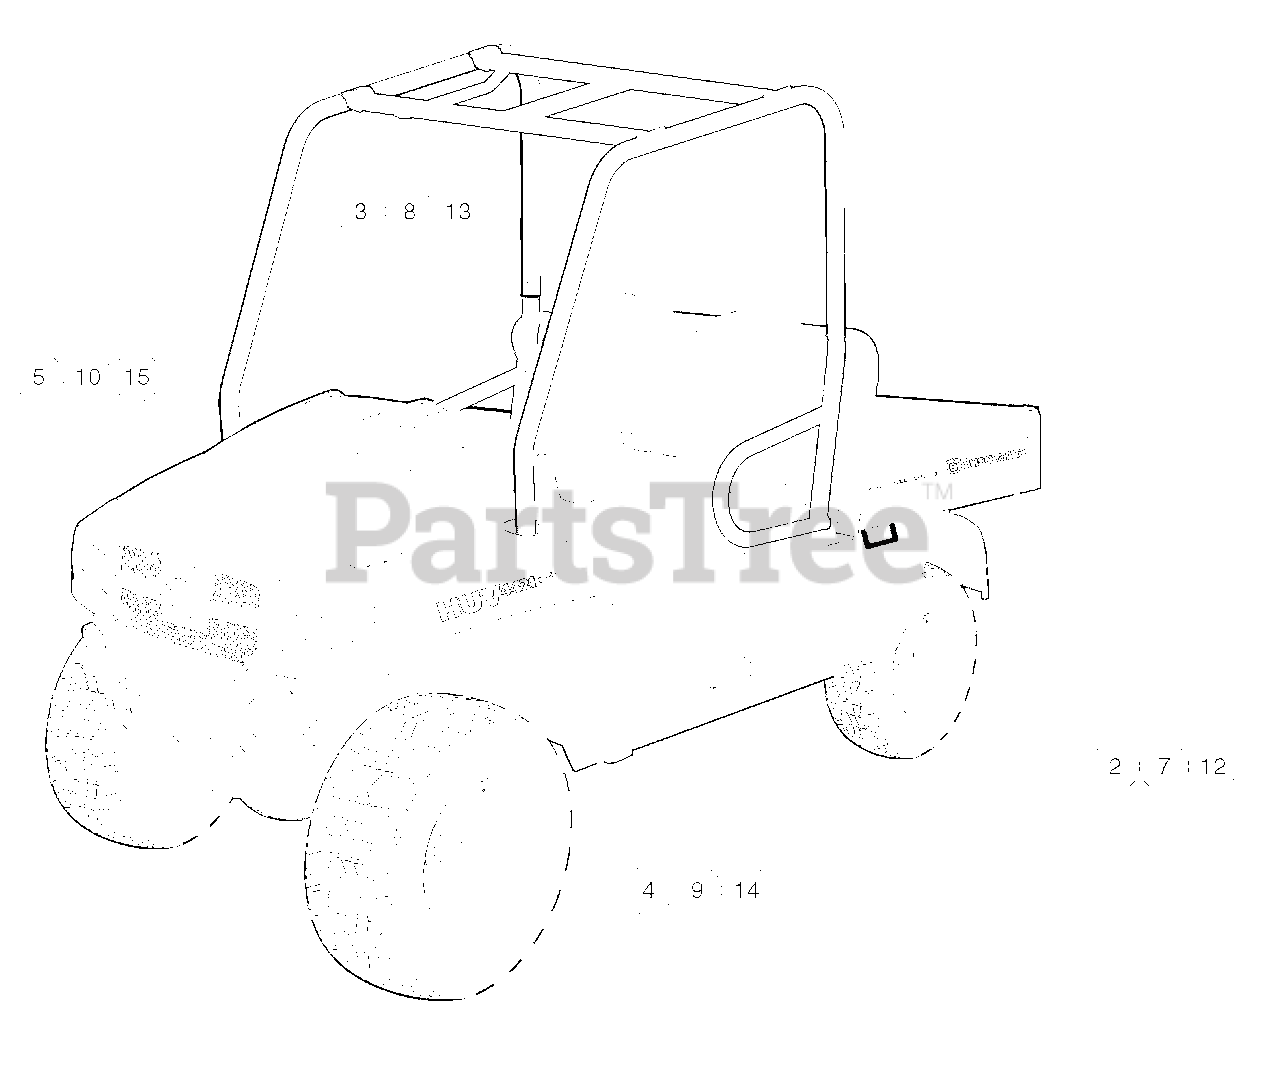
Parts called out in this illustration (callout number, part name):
1	Instl,decal,huv4421dxp,moff
2	Decal, Bed, Huv, Moff, Ds
3	Decal, Bed, Huv, Moff, Ps
4	Decal, Huv, 4421dxp, Moff, Ds
5	Decal, Huv, 4421dxp, Moff, Ps
6	Instl,decal,huv4421dxp,orange
7	Decal, Bed, Huv, Orange, Ds
8	Decal, Bed, Huv, Orange, Ps
9	Decal,huv 4421dxp, Orange, Ds
10	Decal,huv 4421dxp, Orange, Ps
11	Instl,decal,huv4421dxp,olv Grn
12	Decal, Bed, Huv, Olv Grn, Ds
13	Decal, Bed, Huv, Olv Grn, Ps
14	Decal,huv 4421dxp, Olv Grn, Ds
15	Decal,huv 4421dxp, Olv Grn, Ps
